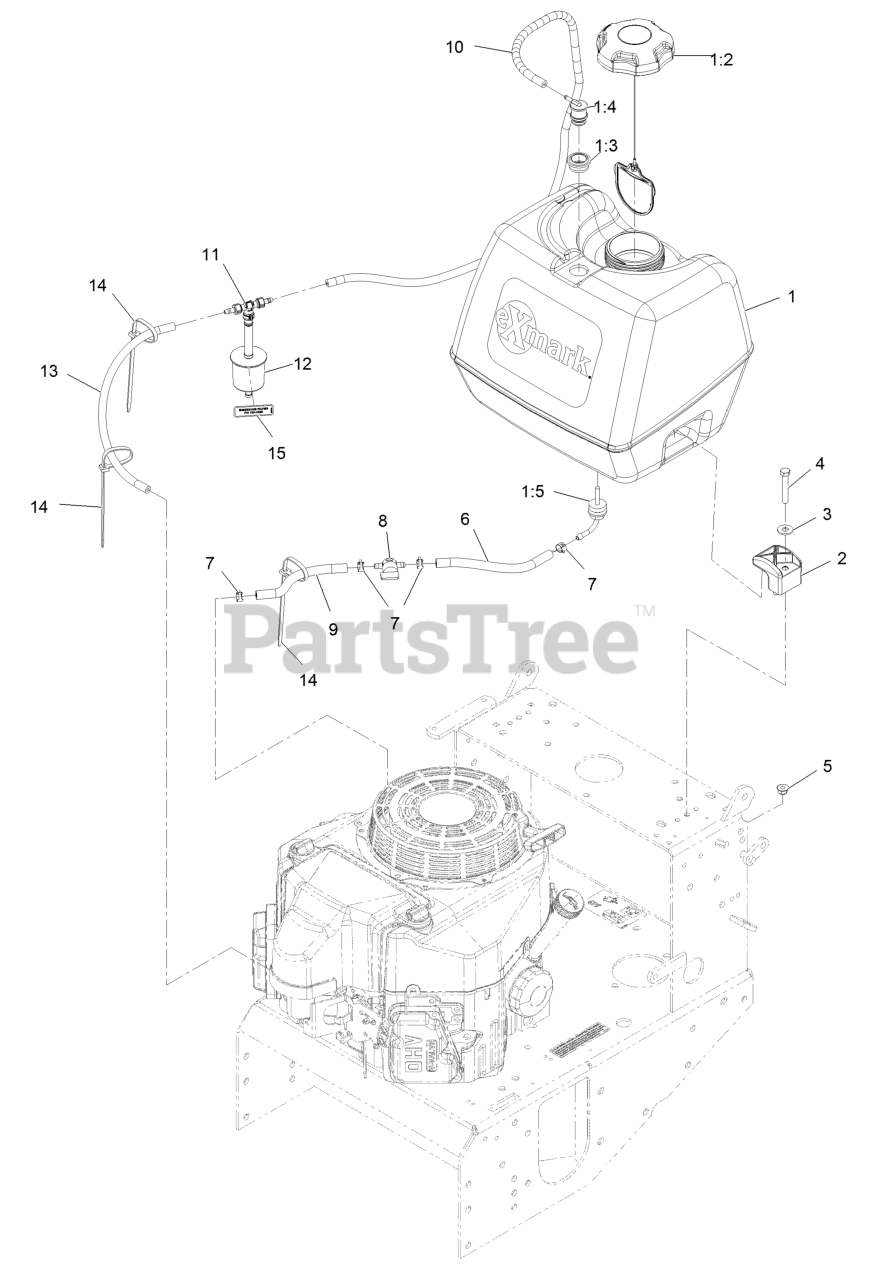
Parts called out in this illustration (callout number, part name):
1	ASM, FUEL TANK
1:3	GROMMET
1:4	VALVE-VENT, FUEL
1:5	FITTING-FUEL, BULKHEAD
3	WASHER-FLAT
4	SCREW-HH
5	NUT-HF, NI
6	HOSE-FUEL
7	CLAMP-HOSE
8	VALVE-FUEL
9	HOSE-FUEL
10	HOSE-EMISSIONS
11	TEE AND CHECK
12	FILTER-FUEL
13	HOSE-FUEL
14	TIE-PLASTIC
15	DECAL-FILTER, EMISSIONS
